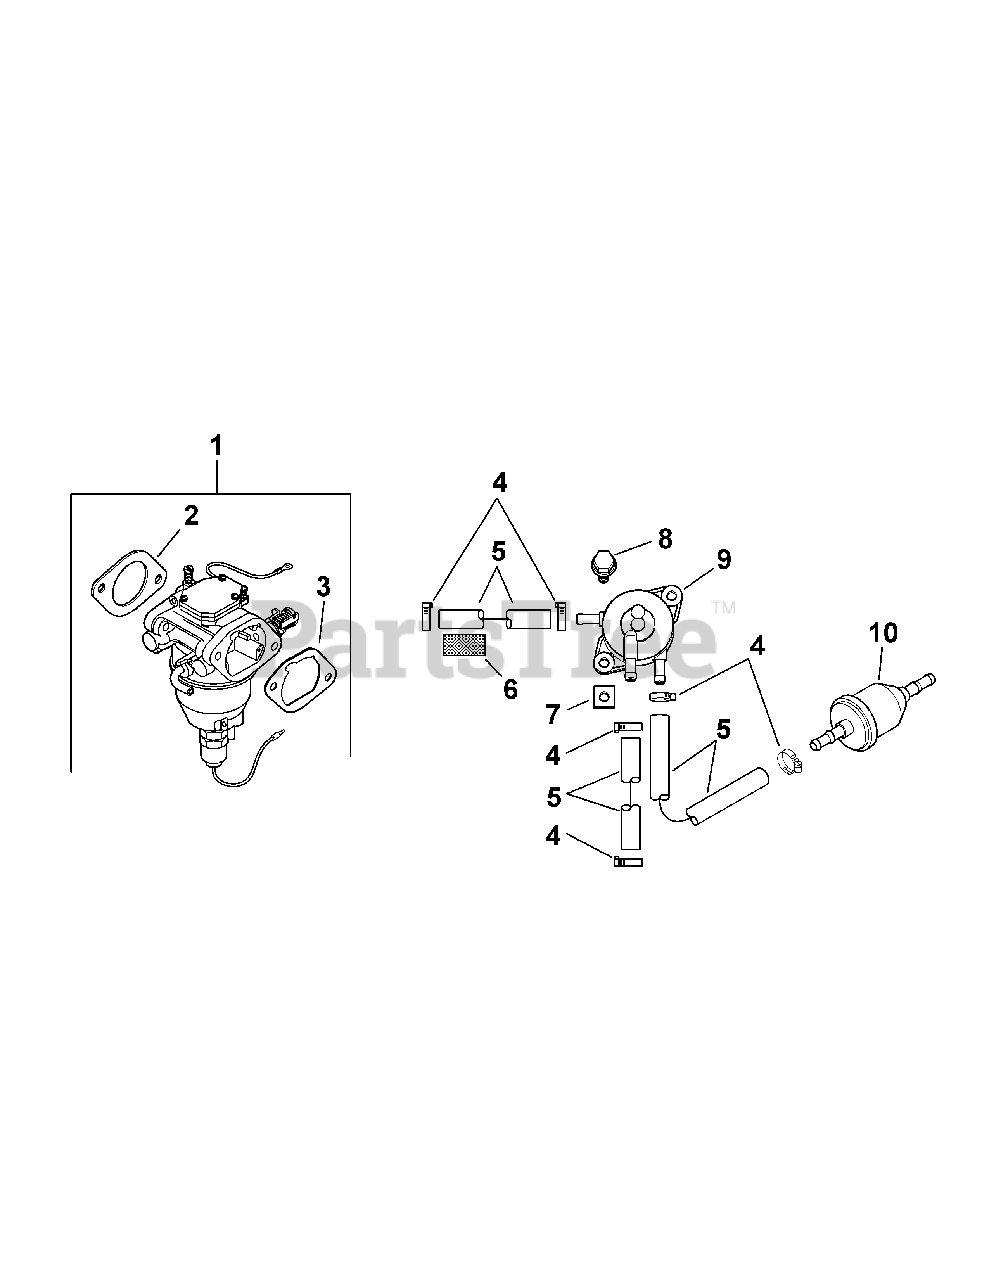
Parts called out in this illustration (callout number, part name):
1	Kit, Carburetor (Includes 2,3)
2	Gasket, Carburetor
3	Gasket, Air Cleaner Base
4	Clamp, Spring Hose 1/2"
5	Line, Fuel
6	Insulating Sleeve
7	Nut, Plastic-Black
8	Screw, Tap M6x1.7x18
10	Filter, Fuel
